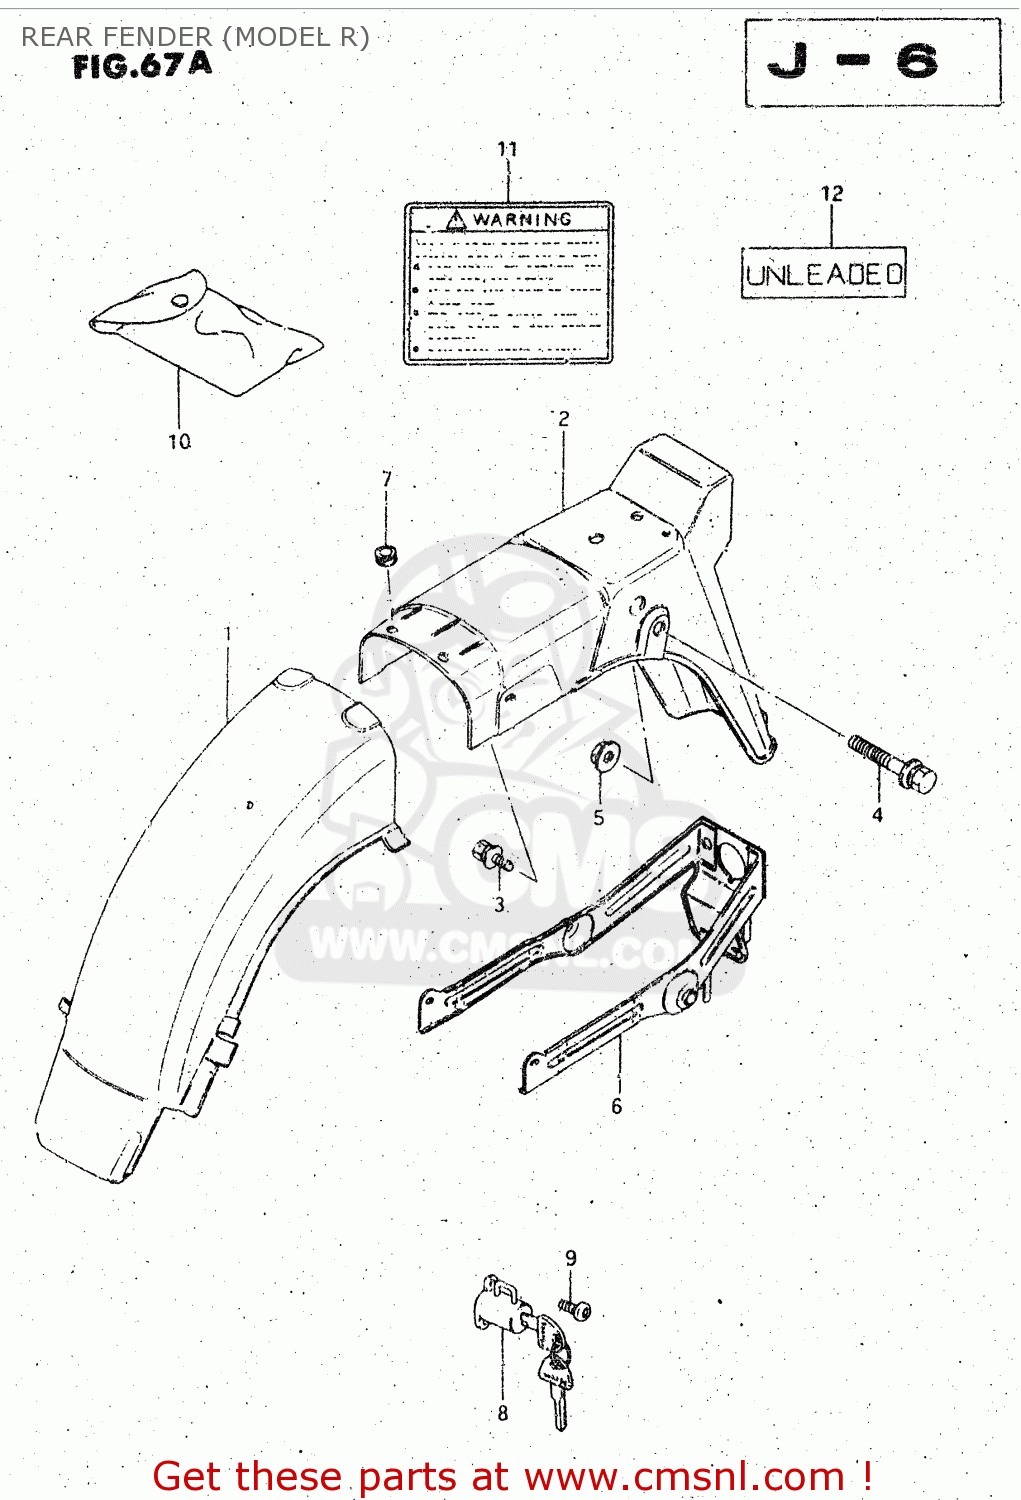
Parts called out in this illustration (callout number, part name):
1	BODY,FR
2	BODY,RR FENDER RR
3	BOLT
4	BOLT
5	NUT
6	REINFORCEMENT,RR FENDER
7	CUSHION
8	LOCK SET,HELMET
9	SCREW
10	TOOL ASSY
11	LABEL
12	LABEL,CAUTION
